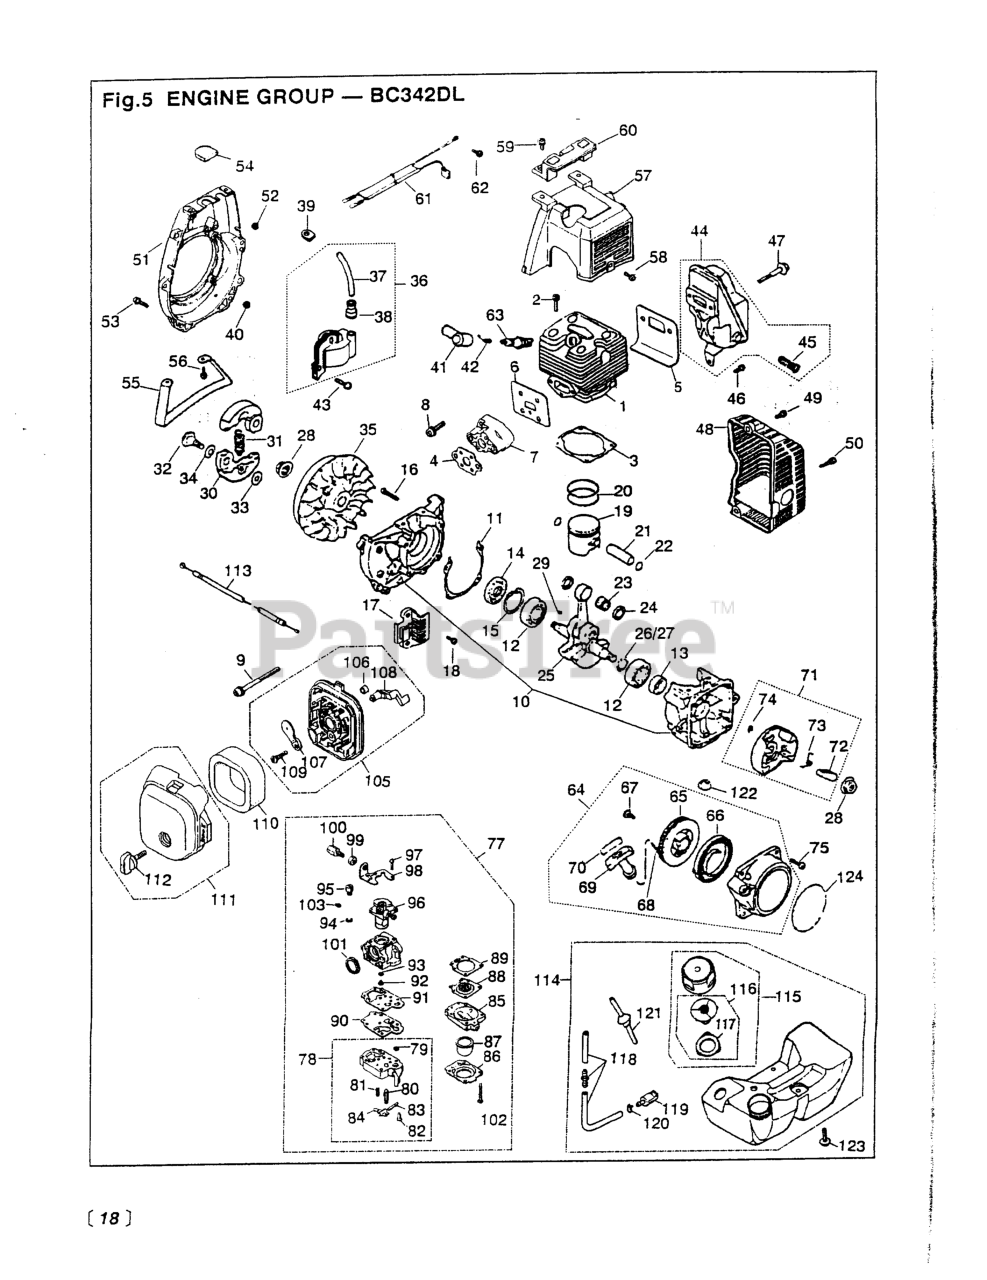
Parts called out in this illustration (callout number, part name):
1	CYLINDER (RPLS -12111)
2	BOLT M5 x 20 (RPLS -12280)
3	GASKET
8	SCREW, M5 x 25
9	SCREW, M5 X 55
10	CRANKCASE (RPLS -21101)
14	SEAL, OIL (RPLS 1200-21220)
15	RING, SNAP, M32 x 1.2
16	BOLT, M5 X 30
17	GUARD (RPLS-21310)
18	SCREW,M5 X 14 (RPLS 1400-15510
20	RING, PISTON
21	PIN
22	RING, SNAP
23	BEARING
24	WASHER (RPLS 3310-41341)
25	CRANKSHAFT CO
26	SHIM (NO LONGER AVAILABLE)
29	KEY
31	SPRING, CLUTCH
32	SCREW
33	WASHER
36	COIL ASSEMBLY
38	CAP
39	GROMMET
42	SPRING
43	SCREW, M5X20 (RPLS.1400-75510)
44	MUFFLER ASSEMBLY
45	ARRESTER
46	SCREW, M5 X 12
48	COVER, MUFFLER
49	BOLT M5 x 20 (RPLS -12280)
50	BOLT
51	COVER, FAN
53	BOLT M5 x 20 (RPLS -12280)
56	BOLT (REPLACES 01252-30514)
58	SCREW, M5 X 12
59	SCREW, M5X20 (RPLS.1400-75510)
60	HEAD GUARD
62	SCREW, M5 X 12
64	RECOIL ASSEMBLY
65	REEL
66	SPRING, SPIRAL
67	SCREW (RPLS -75150)
69	KNOB
71	PULLEY ASSEMBLY
72	RATCHET
73	SPRING, RETURN
74	E-RING
75	SCREW, M5X20 (RPLS.1400-75510)
77	CARBURETOR ASSEMBLY (WYJ-118)
78	BODY, PUMP
80	VALVE, INLET
81	SPRING, METERING LEVER
82	SCREW, METERING LEVER PIN
83	JET
84	LEVER
85	BODY, PURGE
86	COVER, PUMP
87	PUMP, PRIMING
88	DIAPHRAGM (USE 4810-81260)
89	GASKET, DIAPHRAGM
90	DIAPHRAGM
91	GASKET, PUMP
92	JET
93	RING, O
94	RING
95	SWIVEL
96	VALVE ASSY
97	SCREW
99	NUT, CABLE ADJUSTER
100	SCREW, CABLE ADJUSTER
101	RING, PACKING
102	SCREW
103	WASHER
106	SLEEVE
107	PLATE, CHOKE (RPLS-82130)
108	LEVER, CHOKE
109	SCREW (REPLACES 50030272)
110	ELEMENT
113	CABLE COMP (RPLS 1633-83100)
116	VALVE COMPLETE
117	PACKING (RPLS -85321)
119	FILTER ASSY
120	CLIP (REPLACES 2841-31280)
122	WASHER
123	SCREW, M5 X 22
124	LABEL BC342DL (RPLCS. -75411)
